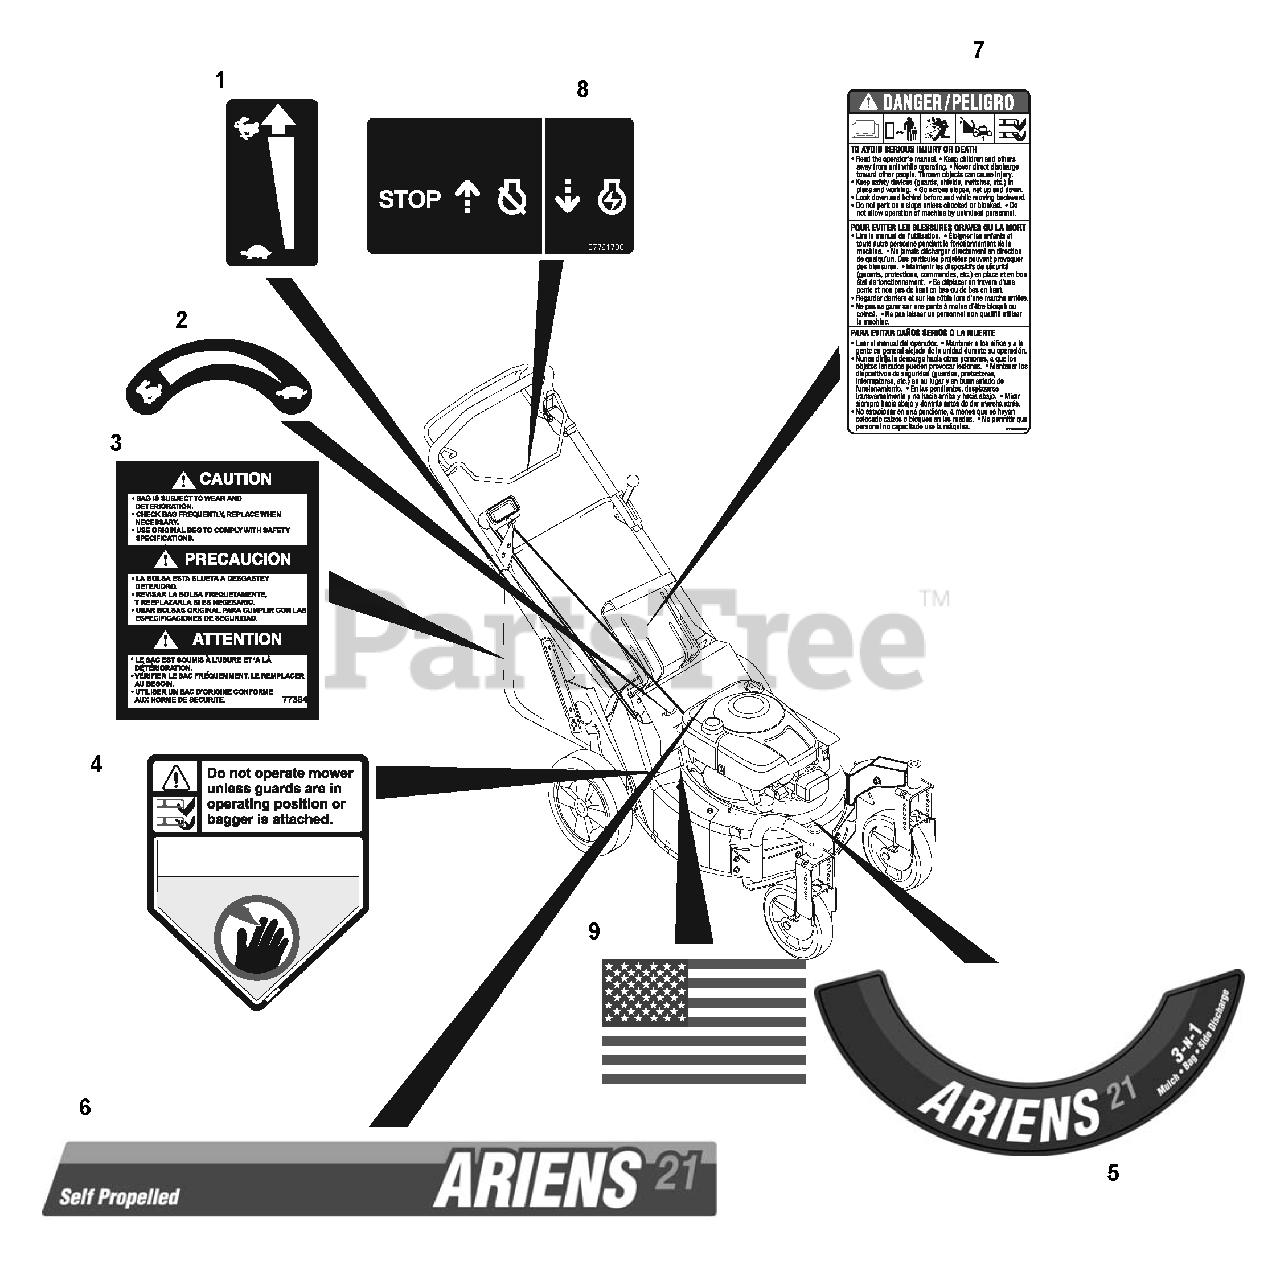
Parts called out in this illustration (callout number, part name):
1	DECAL-SPEED CONTROL
2	DECAL, TURTLE & RABBIT
3	LABEL - BAGGER 21"
4	DECAL, CPSC DANGER
5	DECAL, ARIENS DECK
6	DECAL, DRIVE COVER SP
7	DECAL, BILINGUAL DANGER
8	DECAL - ENGINE CONTROL
9	DECAL, AMERICAN FLAG
